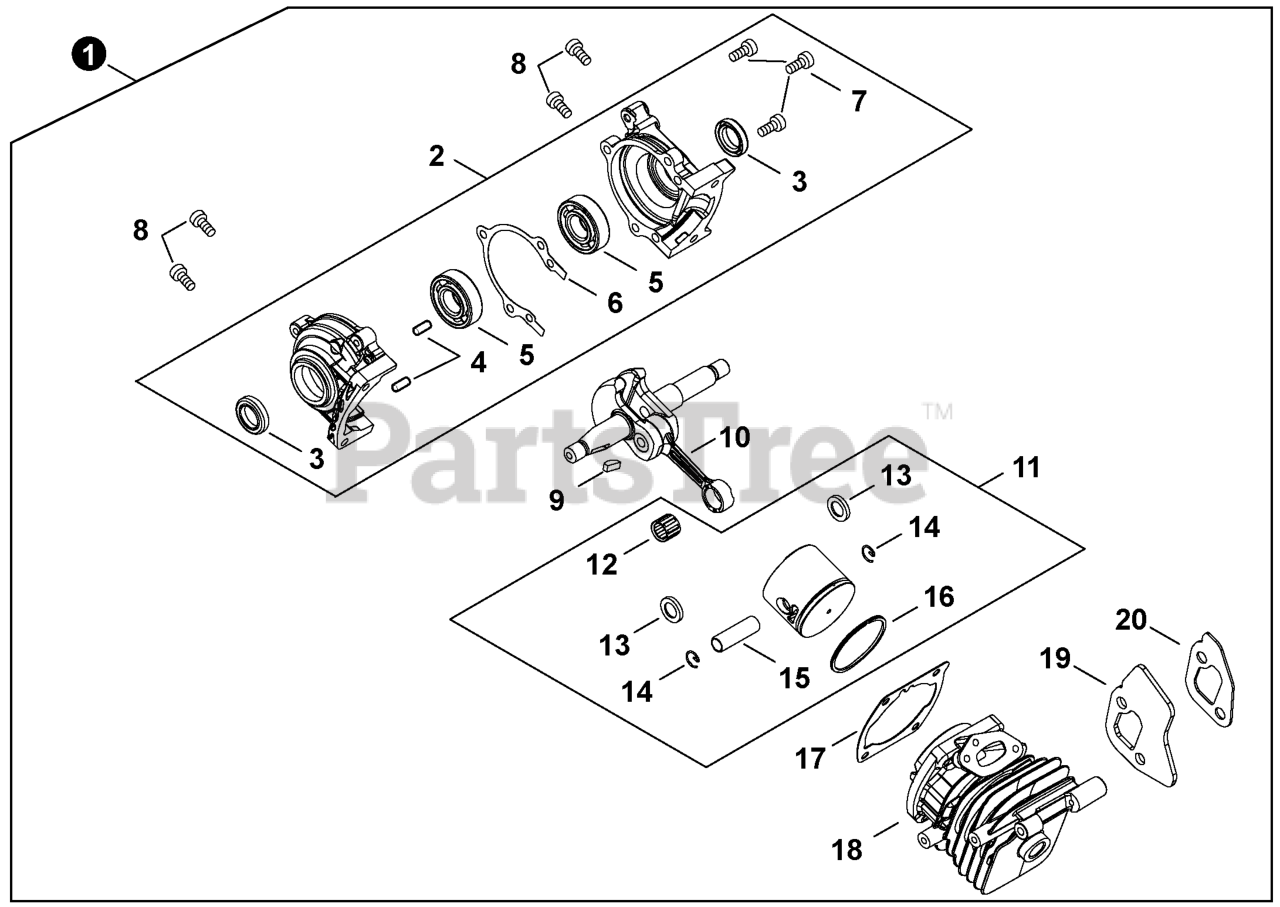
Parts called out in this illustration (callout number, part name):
1	SHORT BLOCK
2	CRANKCASE SET
3	SEAL, OIL 12
4	PIN, LOCATING 4x8
5	BEARING, BALL 6001
6	GASKET, CRANKCASE
7	BOLT, TORX 4x16
8	BOLT, TORX 4x16
9	KEY, WOODRUFF
10	CRANKSHAFT
11	PISTON KIT
12	BEARING, NEEDLE 8
13	WASHER, THRUST
14	RING, SNAP
15	PIN, PISTON 8
16	RING, PISTON
17	GASKET, CYLINDER
18	CYLINDER
19	HEAT SHIELD, EXHAUST
20	GASKET, EXHAUST
